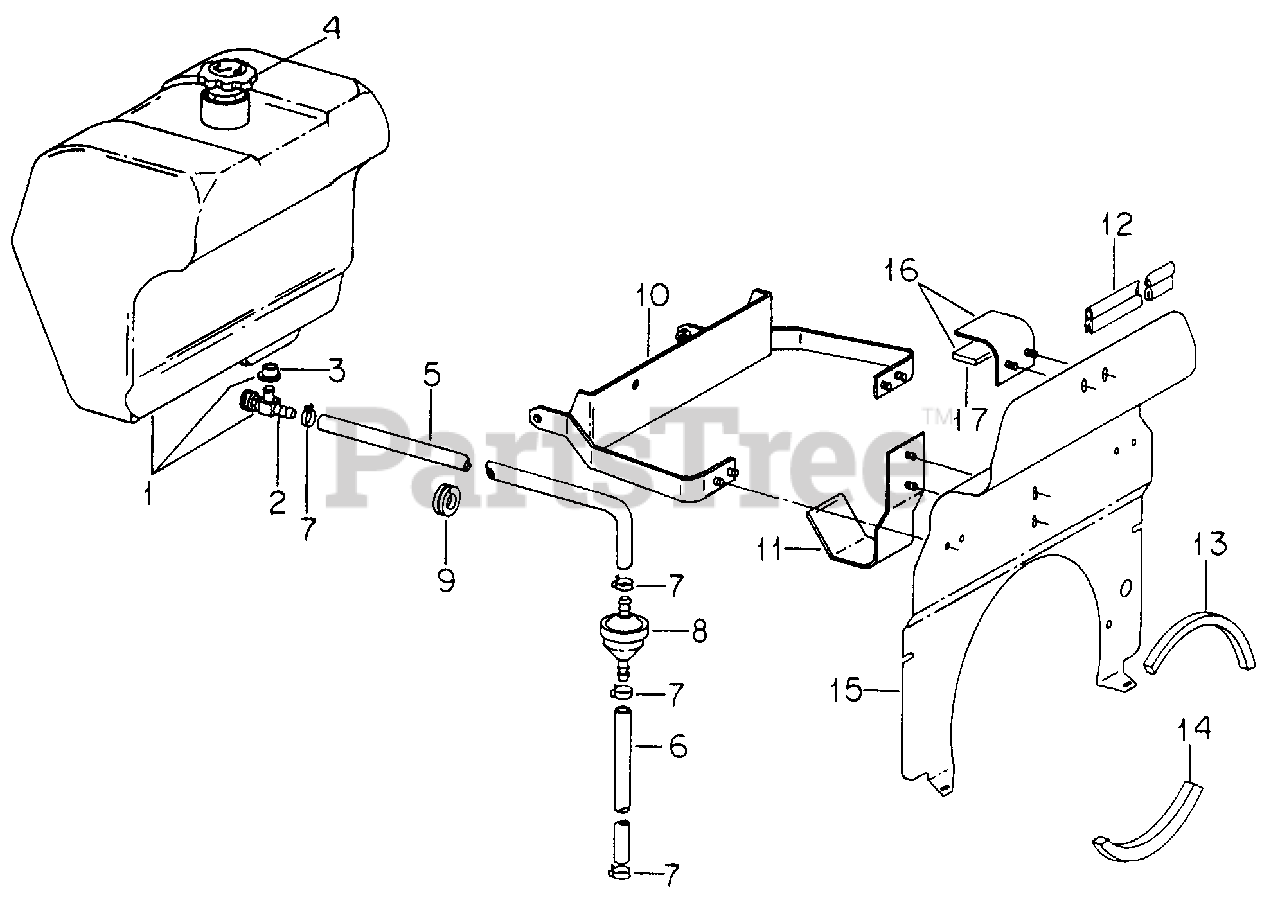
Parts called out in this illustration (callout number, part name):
1	Tank Assy, Fuel
2	Valve, Shut-Off
3	Bushing
4	Cap w/Gauge Assy
5	Line, Fuel
6	Line, Fuel
7	Clamp, Hose
8	Filter, Fuel
10	Support Assy, Fuel Tank
11	Support Assy, Fuel Tank Bottom
12	Seal, Heat Baffle
13	Strip, Foam Gasket Sealing
14	Strip, Foam Gasket Sealing
15	Deflector, Heat
16	Clamp Assy, Fuel Tank
17	Strip, Fuel Tank Pad
